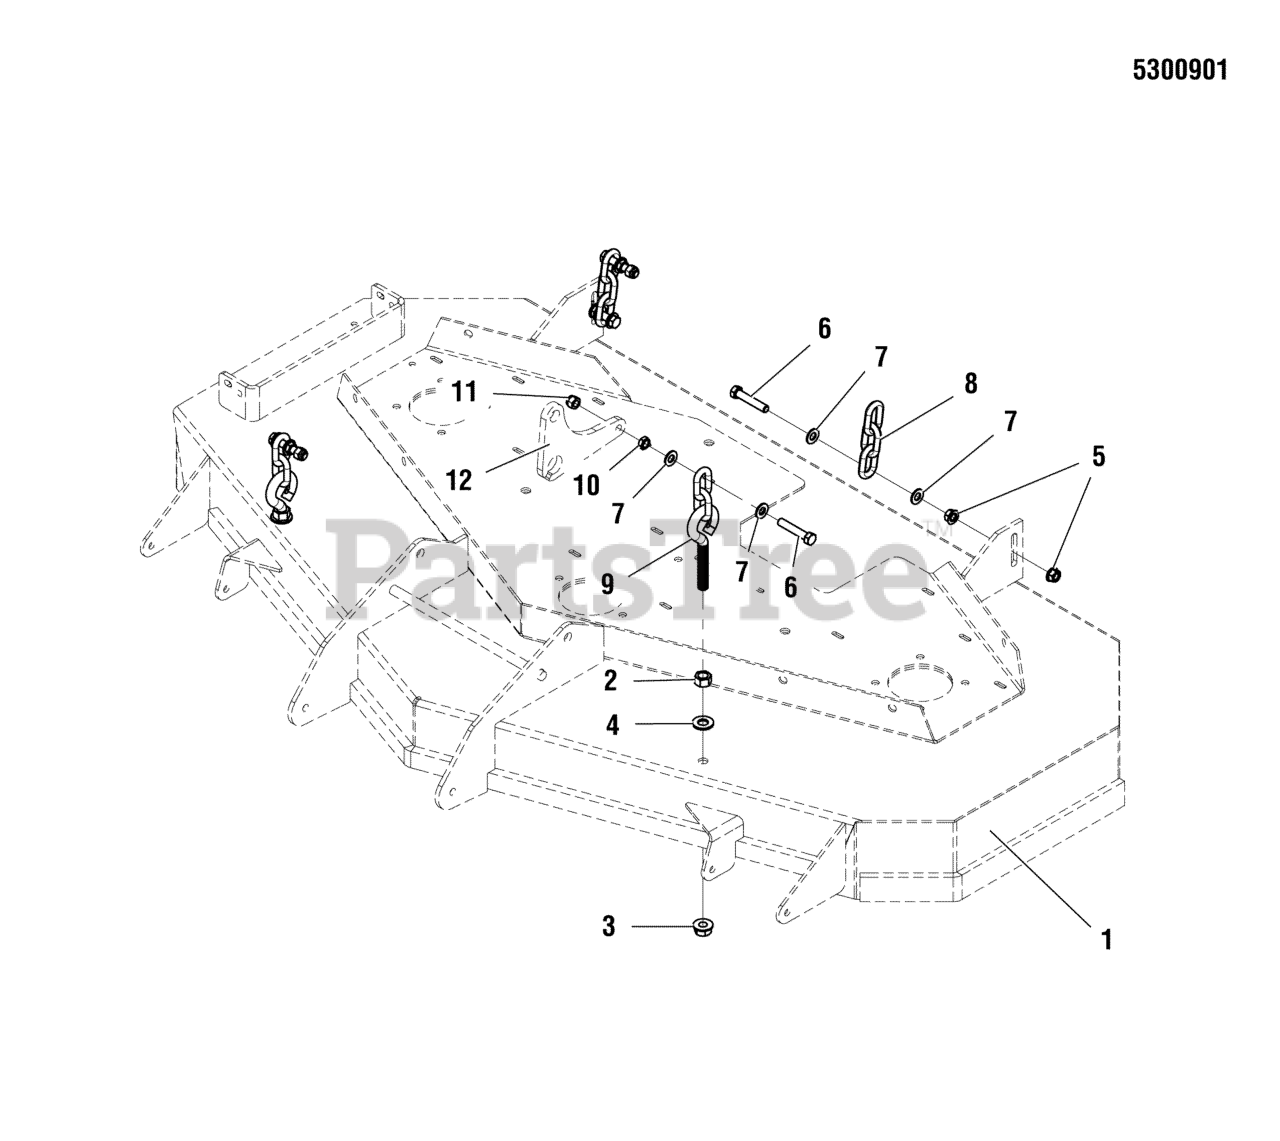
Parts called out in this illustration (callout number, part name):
1	MOWER DECK
2	NUT, 1/2-13 HEX
3	NUT, Hex Flange, Nylock, 1/2-13
4	WASHER, 1/2 SAE
5	NUT, 3/8-16 HEX SERRATED FLANGE
6	BOLT, 3/8-16 X 2, GD5, CZ
7	WASHER, 3/8 SAE
8	CHAIN, 5/16 GD30, 3 LINKS
9	HANGER, FRONT DECK-2LINK, 5.5" EB
10	NUT, 3/8-16 HEX JAM
11	NUT, 3/8-16 HEX NYLON LOCK
12	DECK LIFT PIVOT
